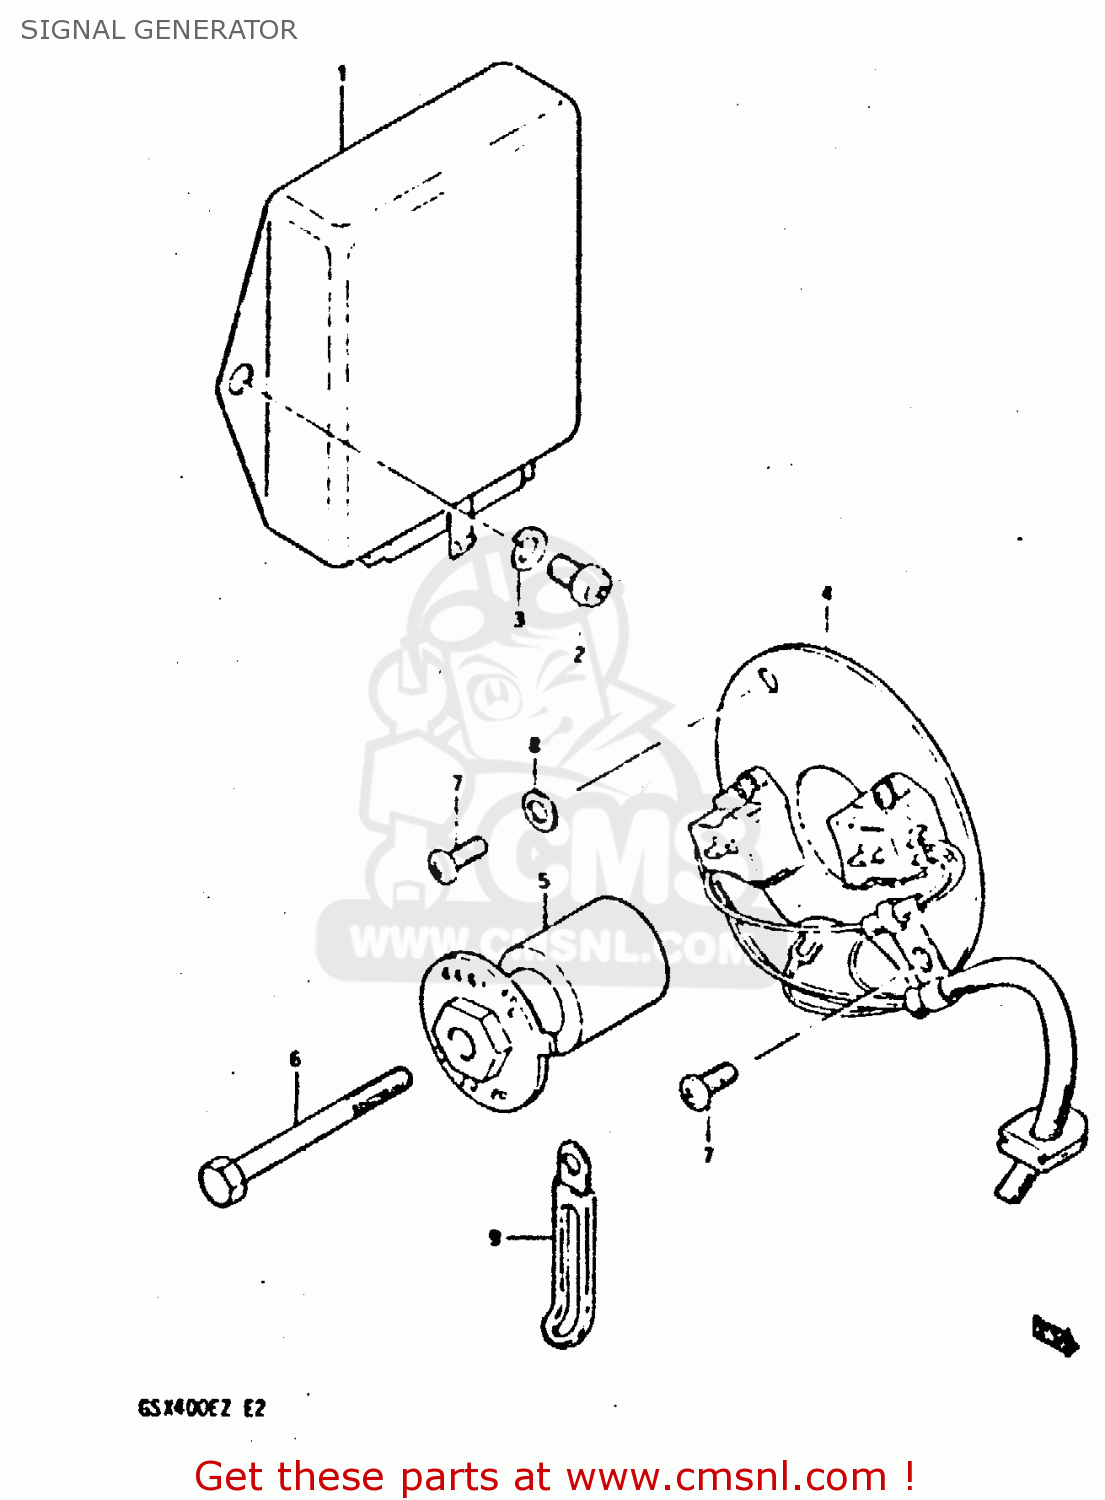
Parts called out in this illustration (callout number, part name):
1	IGNITER UNIT A
2	SCREW
3	LOCK WASHER
4	SIGNAL GENERATOR ASSEMBLY
5	ROTOR, SIGNAL
6	BOLT 6X60
7	SCREW(5X12)
8	WASHER
9	CLAMP L:35
